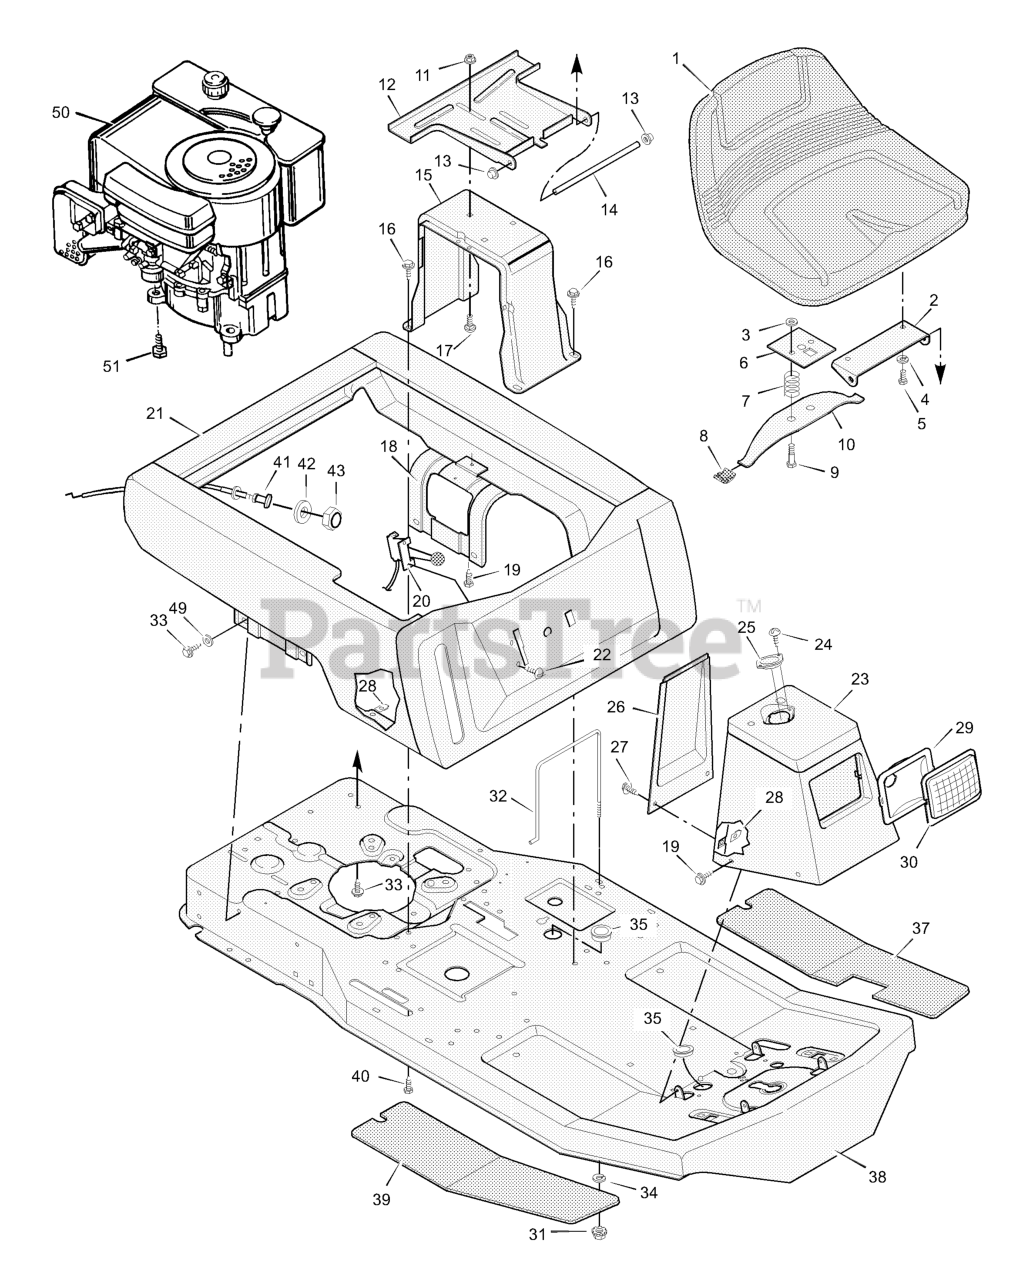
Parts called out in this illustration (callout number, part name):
2	Hinge, Seat
3	Retainer
4	Lockwasher
5	Bolt, Hex
6	Plate, Seat Switch
7	Spring, Compression
8	Glide, Seat Spring
9	Bolt, Shoulder
10	Spring, Seat
11	Locknut, Flange
12	Bracket, Seat Pivot
13	Cap, Push On
14	Rod, Seat Hinge
15	Support, Seat
17	Bolt, Carriage
18	Support, Body
20	Throttle Control
23	Console Assembly
25	Bearing, Steering Post
26	Console, Plate
29	Reflector
31	Locknut
32	Clamp, Battery
35	Grommet
37	Mat, Left
38	Frame Assembly
39	Mat, Right
42	Washer
49	Washer
50	Engine *
51	Bolt, Engine Mount
